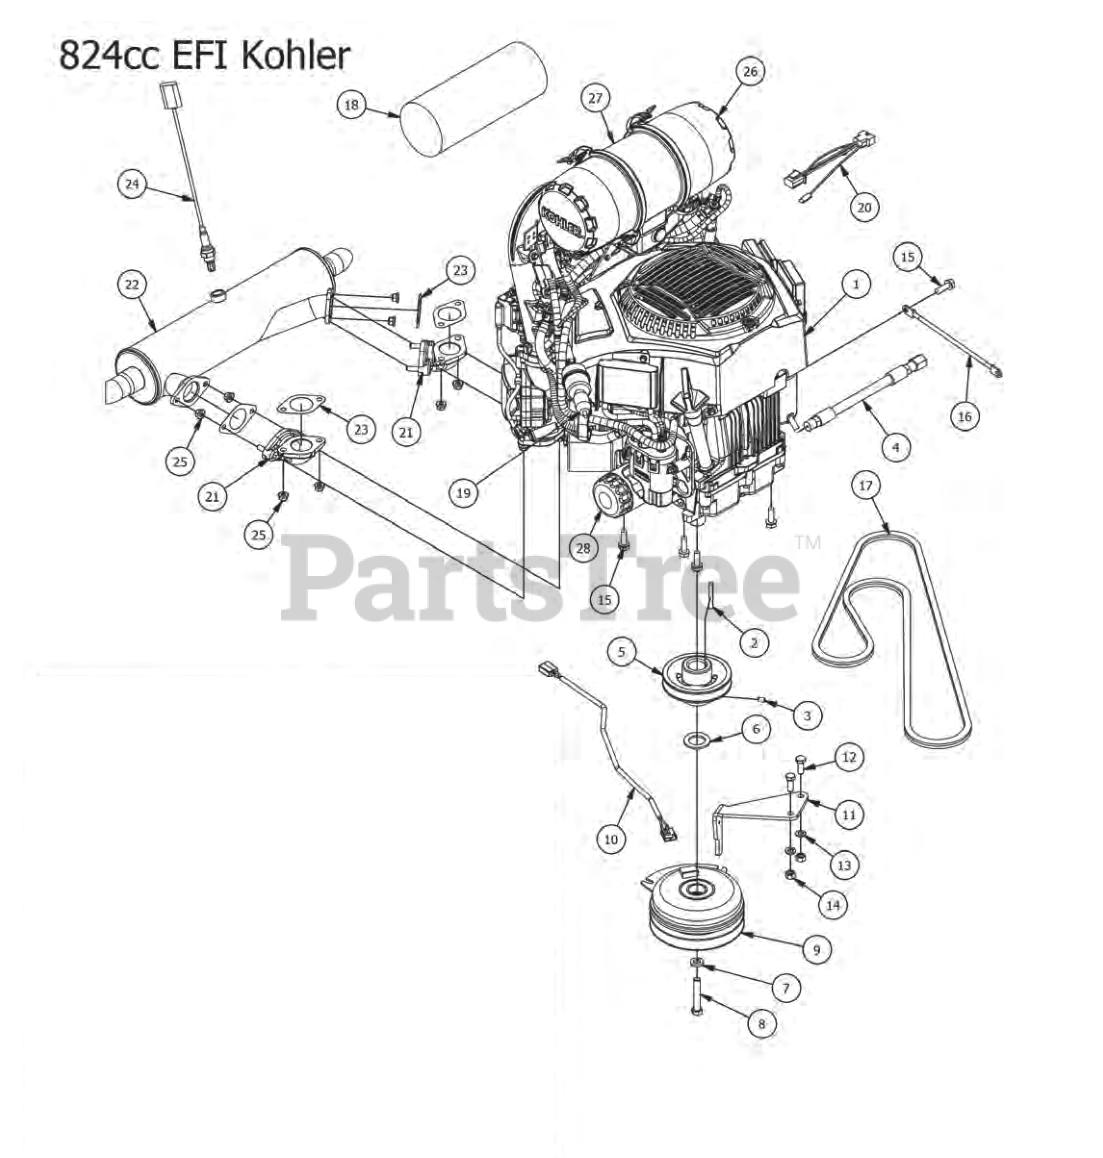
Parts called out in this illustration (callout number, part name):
1	824cc EFI Kohler
2	1/4 x 2 Square key Stock
3	3/8" Set Screw
4	Oll drain Hose
5	4 3/4 Motor Pulley
6	1 1/8" Flat Spacer
7	7/16" Lock Washer
8	7/16" x 2 1/2" Hex Bolt
9	Clutch Assembly
10	Clutch Pigtail
11	PTO Engager Holder
12	3/8" x 1" Hex Bolt
13	3/8" Lock Washer
14	3/8" Hex Nut
15	3/8 x 1 1/8 bolt
16	Starter to chassis cable
18	Canister Air Filter-Outer
19	Universal inline Fuel Filter
20	Harness Adaptor -824cc EFI Kohler
21	Cast 90 Elbow
22	824cc Kohler Exhaust
23	Exhaust Gasket for 824EFI Kohler
24	02 Sensor for 824EFI Kohler
25	M8 125 Mechanical locking Flange Nut
26	Kohler End Cap
27	Kohler Air Canister Complete
28	Oil Filter
